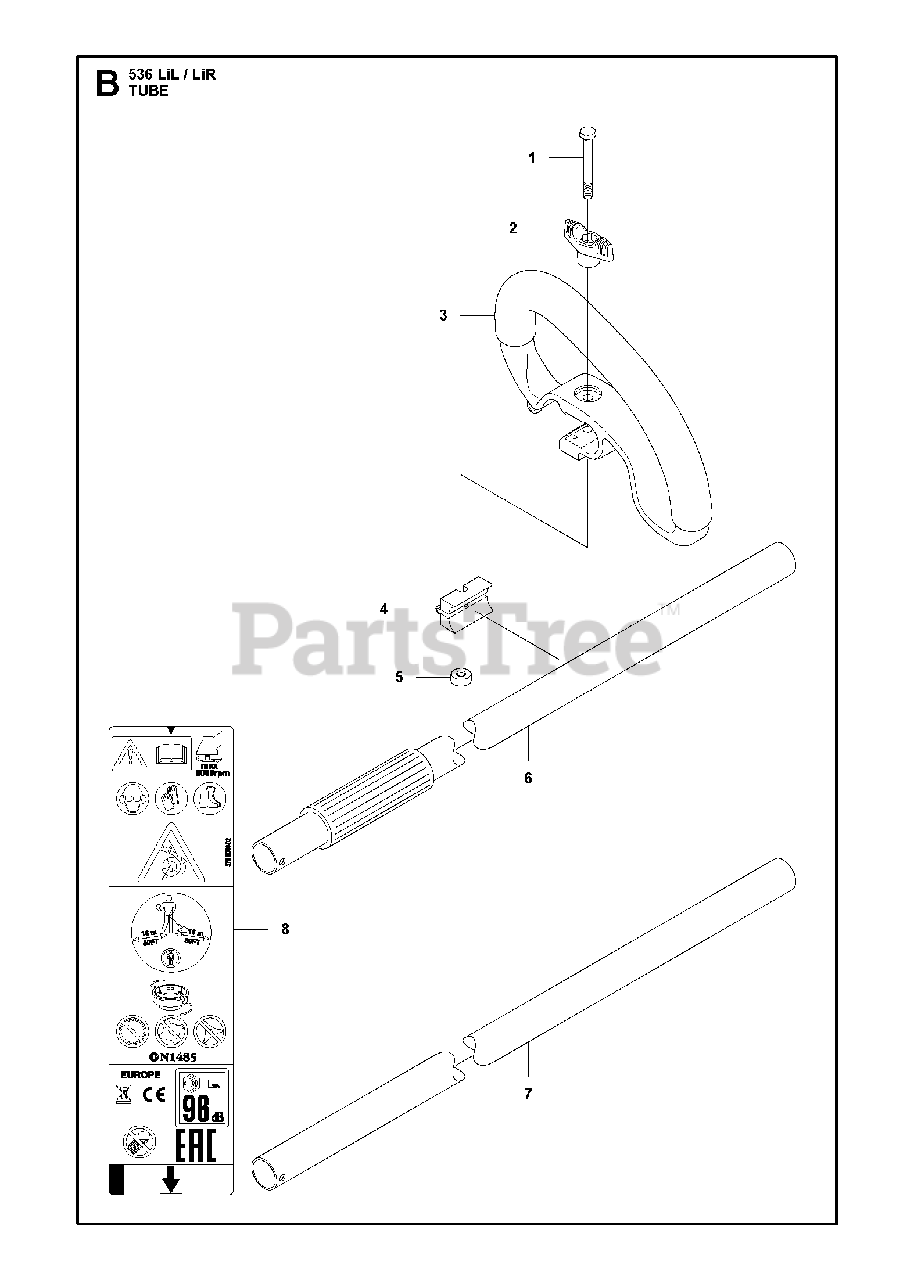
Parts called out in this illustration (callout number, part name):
1	SCREW M6X50
4	SPACER PLASTIC
7	TUBE
